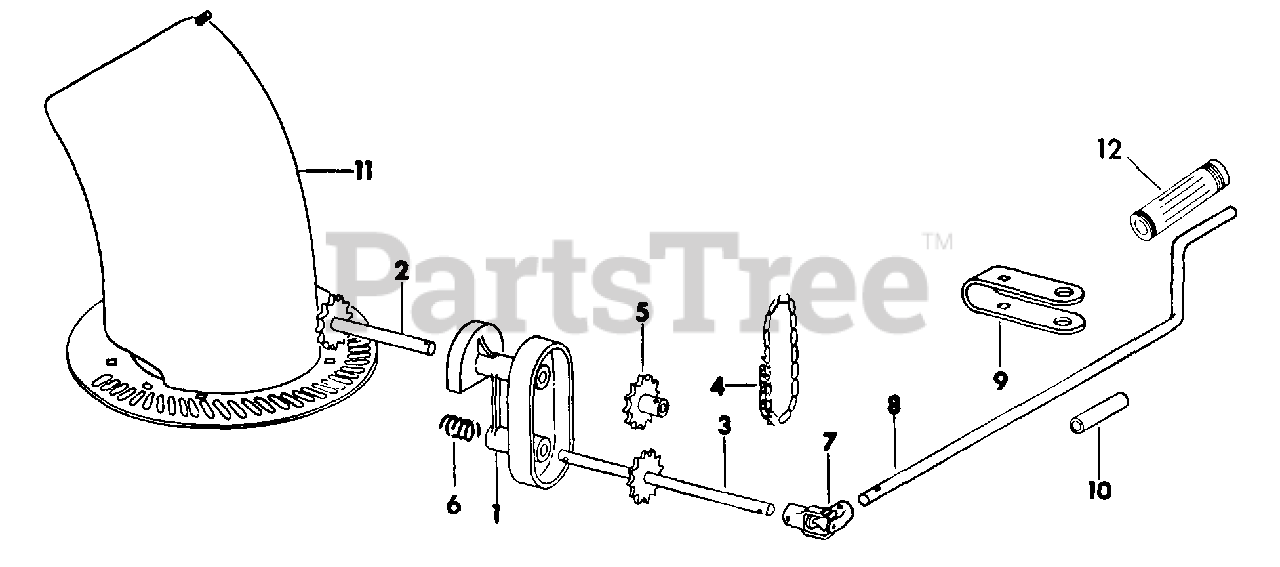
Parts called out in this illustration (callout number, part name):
1	SUPPORT, BEARING
2	SPROCKET - 12 TEETH
3	SPROCKET AND SHAFT - 12 TEETH
4	CHAIN, DRIVE
5	SPROCKET - 12 TEETH
7	UNIVERSAL JOINT
8	HANDLE, CHUTE CONTROL
9	BRACKET, CHUTE CONTROL
10	SLEEVE, CONTROL HANDLE
11	CHUTE, CONTROL
12	GRIP, CHUTE CONTROL HANDLE
